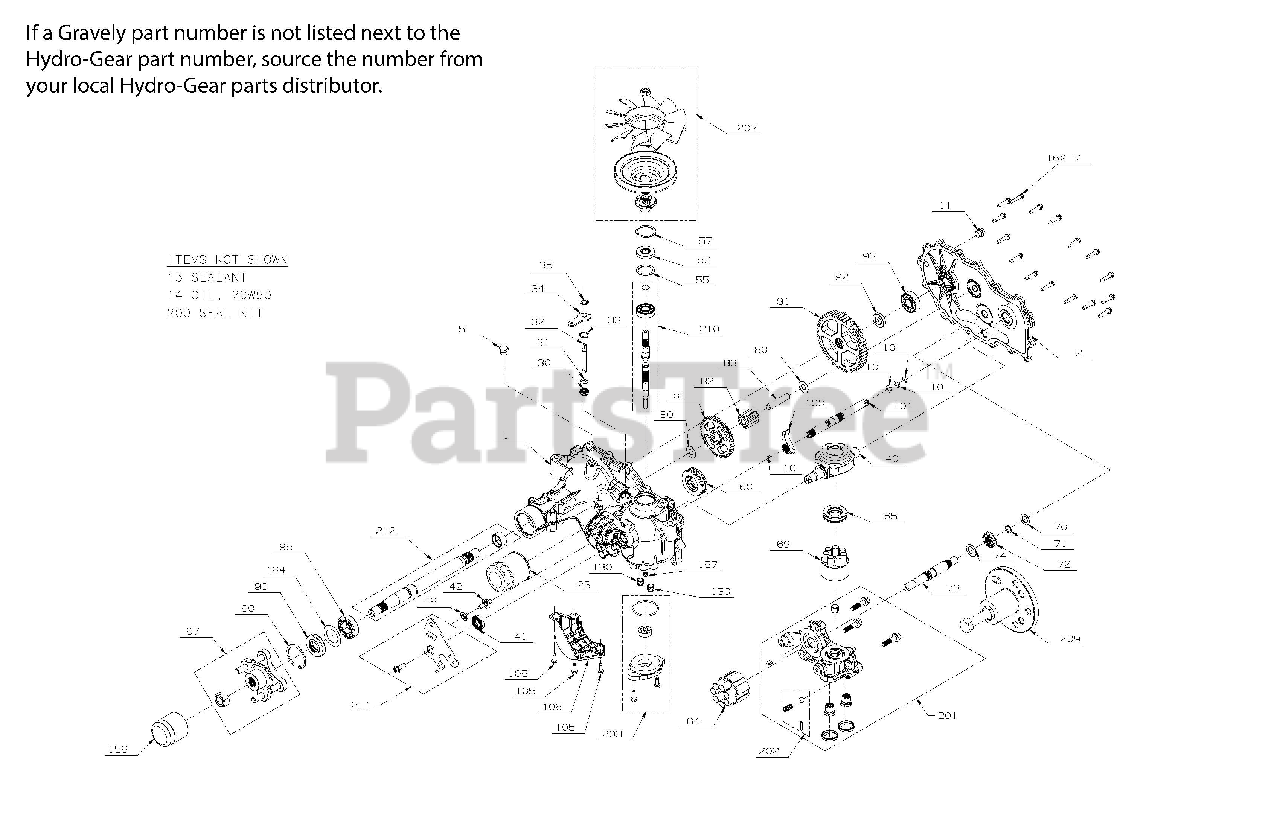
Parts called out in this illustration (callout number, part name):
1	KIT, MAIN HOUSING RH, CHARGE, CONTROL
2	KIT, COVER SIDE RH
7	SCREW,HEX WASHER 1/4-20X1.125
13	SEALANT TUBE 10.1OZ.
23	OIL FILTER, TRANSMISSION
30	SEAL, LIP .375X.75X.25
33	RING, RET .750
34	ARM, BYPASS
35	RING, RTNG .
40	TRUNNION, SWASHPLATE
41	SEAL, LIP 18X32X7
42	STUD. SHORT 5/16-24
48	SPACER
55	WASHER 1.23X1.56X.04
56	SEAL, LIP 17X40X7
57	RING, RET 1.56 INT
60	HG THRUST BEARING (51462)
64	HG 16CC CYLINDER BLOCK (71579)
65	BEARING. THRUST 30 X 52 X 13
69	ASSY, BLOCK 7 PISTON
70	WASHER .63X1.0X.05
71	RING, RET 62 EXT
73	SHAFT, MOTOR
74	WASHER .71 X 1.16 X .04
80	WASHER .5X1.0X.032
83	JACK SHAFT (PIN)
90	RING, RETAINING
93	KIT, BEARING
95	BEARING, BALL 25.4 X 52 X 15
96	SEAL, LIP
97	KIT, HUB 4 BOLT
100	PAWL, BRAKE
101	KIT, BRAKE SHAFT
105	HFHCS 1/4-20X.75
106	GUARD, FILTER, RH
130	TUBE, CHARGE TRIPLE O-RING
157	KIT, GEROTOR SEAL
158	CAP, AXLE
164	WASHER, 1.355 x 2.035 x .021 FLAT
200	KIT, SEAL
201	KIT, CENTERSECTION, RH, CHARGE
202	KIT, CHARGE RELIEF
203	KIT, CHARGE
207	KIT, FAN/PULLEY
209	HUB PULLER 4 BLT HYDGEAR 71459
210	INPUT SHAFT 2800 HYDGEAR 71442
211	KIT, ARM, CONTROL
212	KIT, SHAFT AXLE
